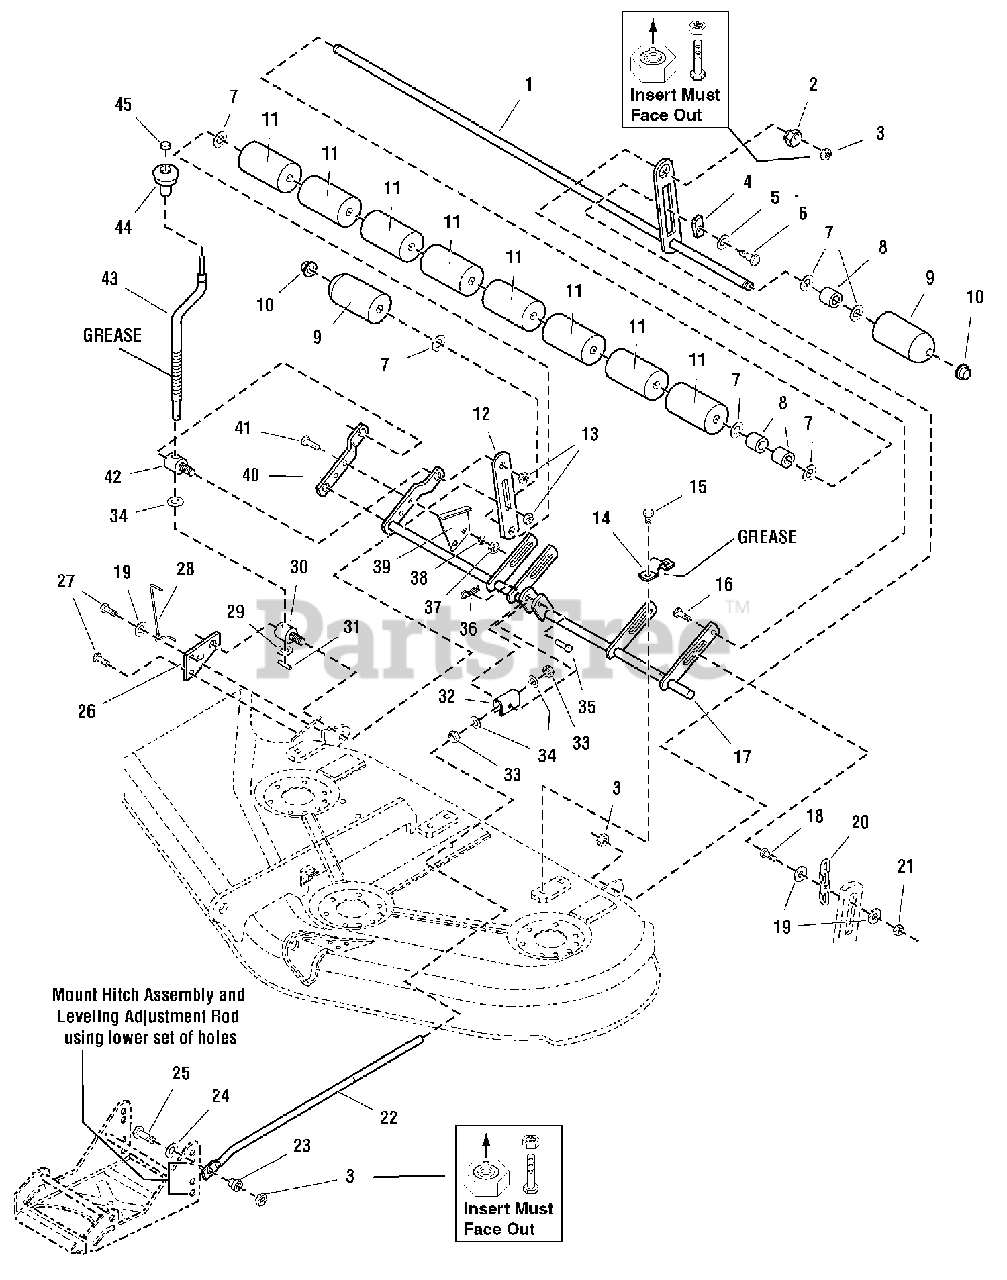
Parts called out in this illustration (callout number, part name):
1	SHAFT ASSEMBLY, Roller, 50", (Includes Ref. No. 10)
2	NUT, Adjuster
3	NUT, Hex Aluminum Insert Lock, 3/8-16
4	SLIDE
5	WASHER, Plain, 1/2
6	BOLT, Shoulder, 3/8-16
7	WASHER, Plain, 1 1/4
8	SPACER, 21/32 x 5/32 x 5/8
9	ROLLER, Rounded End
10	NUT, Push
11	ROLLER
12	BAR, Roller
13	NUT, Hex Flange, 2 Way Lock, 1/2-13
14	STRAP, Mower Arm Assembly
15	CAPSCREW, Hex Head Taptite, 5/16 -18 x 3/4
16	CARRIAGE BOLT, 3/8-16 x 1-1/2
17	ARM ASSEMBLY, Mower
18	CAPSCREW, Hex Head, 5/16-18 x 1-1/4, G8, 1/2 Thread
19	WASHER, 5/16, Black
20	CHAIN, 4 Link, 6 3/32 Long
21	NUT, Hex Lock ESNA Light, 5/16-18
22	ROD, Adjustment
23	SPACER, 3/8 x 3/4 x 15/16
24	WASHER, 3/8
25	CAPSCREW, Hex Head, 3/8-16 x 1-3/4
26	PLATE, Mower Support
27	CAPSCREW, Hex Head Taptite, 5/16-18 x 1-1/4
28	INDICATOR, Cutting Height
29	WASHER, Detent
30	TRUNNION
31	PIN, Roll, 1
32	TRUNNION
33	NUT, Hex, Jam, 1/2-13
34	WASHER, 11/32
35	PIN, Clevis
36	CLIP, Hair Pin
37	NUT, Hex, 5/16-18
38	WASHER, Lock, 5/16
39	BRACKET, Cutting Height
40	ARM, Rear, Mower, RH
41	CAPSCREW, Hex Head, 5/16-18 x 1-1/4
42	TRUNNION, Threaded
43	CRANK, Cutting Height
44	KNOB, Height Crank
45	PAL NUT
